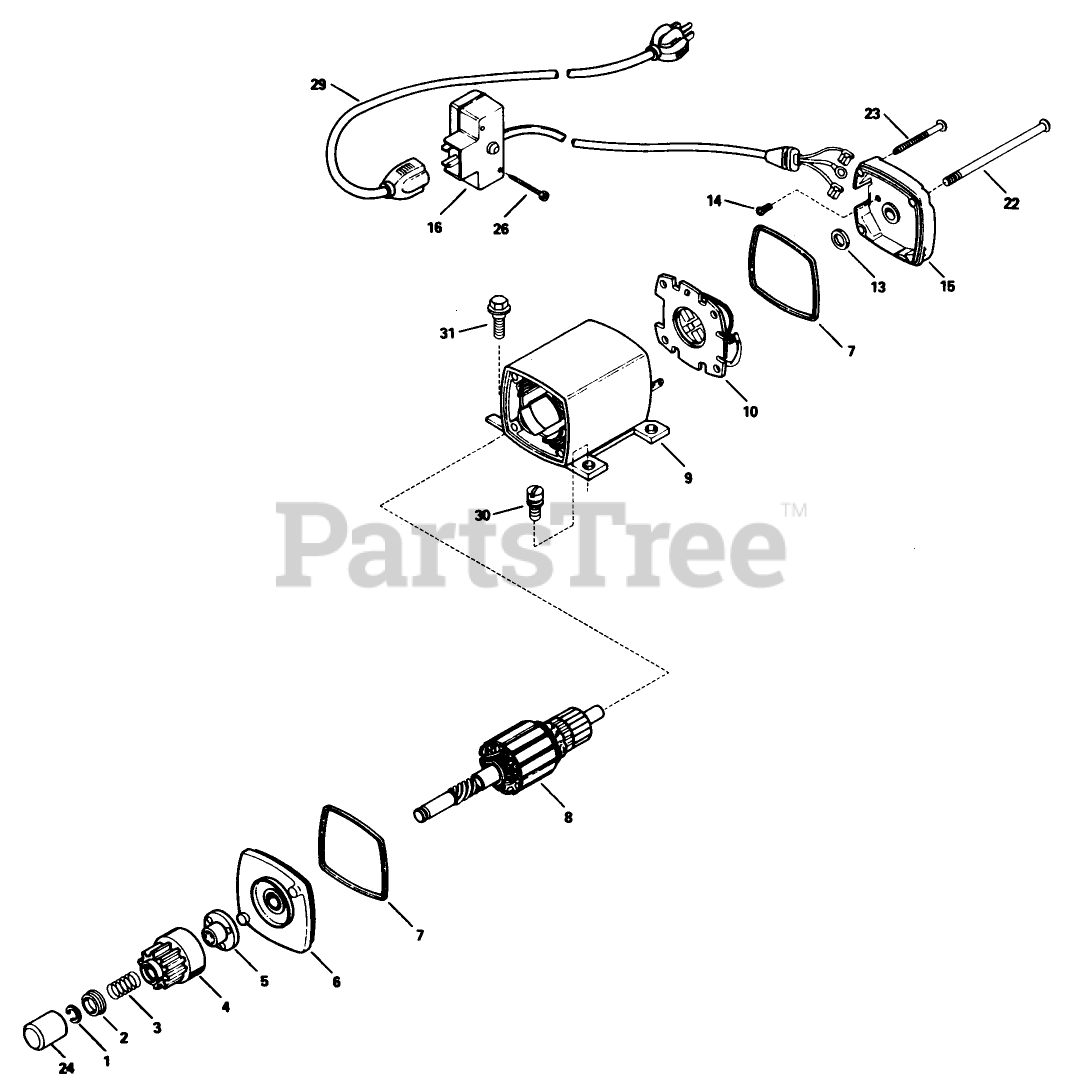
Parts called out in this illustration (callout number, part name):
1	Ring-Retainer
2	Retainer-Spring
3	Spring-Anti Drift
4	Gear
5	Nut-Engaging
6	Cap Assembly-Cap End (Incl. Ref. #7)
7	O-Ring
8	Armature
9	Housing Assy.
10	Card ASM
13	Washer-Thrust
14	Screw-Ground
15	Cap Assembly (Incl. Ref. #7)
16	Box Assembly-Switch (Incl. Ref. #26)
22	Bolt-Case
23	Screw-Ground
24	Cover-Dust
26	Screw
29	Cord-Extension
30	Screw
31	Screw (1/4-20x1/2)
